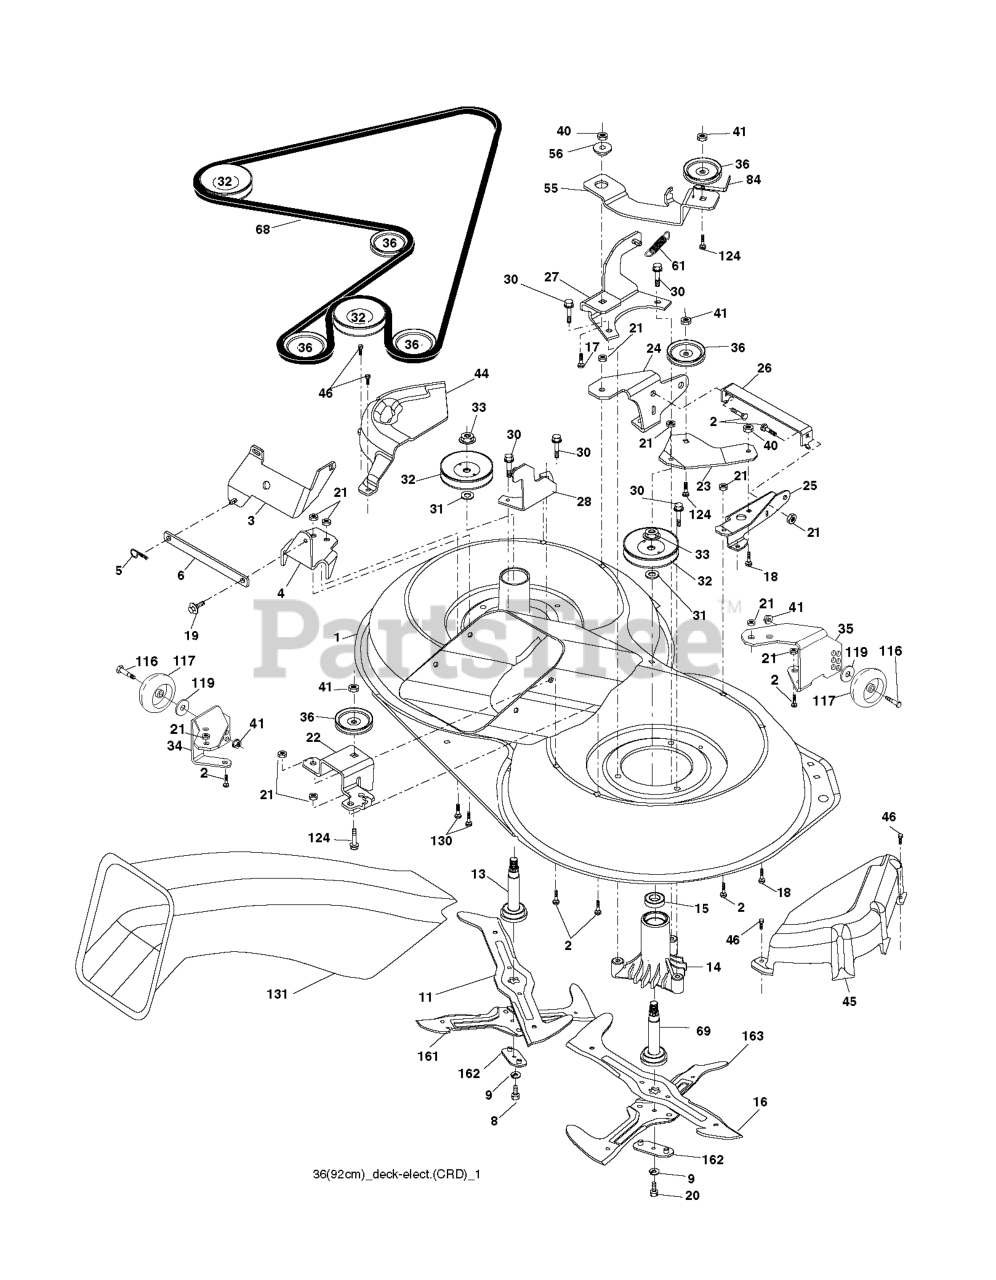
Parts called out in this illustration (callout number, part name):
2	RP BOLT 5/16-18 X3/4 ZN/YEL GR
5	RETAINER-SPRNG RB
6	BAR.SWAY.92.CRD
8	BOLT.3/8-24X1.25 GR8
9	LOCKWASHER
13	SHAFT ASM VENT
14	HOUSING.MANDREL.VENTED (MACHD)
17	BOLT.3/8-14X1.25
18	BOLT
19	BOLT SHD 5/16-18
20	BOLT.3/8-24X1.25GR8. LHTHRD
21	LOCKNUT
26	SUPPORT
30	SCREW, WASHER HEAD
31	WASHER.SPACER.MANDREL
33	NUT.FLANGE.LOCK.TOP
36	PULLEY.IDLER.4.25
41	NUT LOCK FLG 3/8-16 UNC
45	COVER.MANDREL.RH.CRD
46	SCREW.1/4-20X5/8
55	ARM.IDLER.92 CRD.2006
56	SPACER.RETAINER.MOWER
61	SPRING
68	BELT.DRIVE.92CM.CRD.2006
69	SHAFT.ASM.W/LWR.BRG.RH.THREAD
84	KEEPER, BELT IDLER
116	BOLT.SHOULDER.3/8-16X3-5/8.
117	RP WHEEL. GUAGE RALLY
119	WASHER
124	BOLT.3/8-16X1.50
130	BOLT.CARR.SQNK.5/16-18UNC.X3/4
131	CHUTE BAGGER
